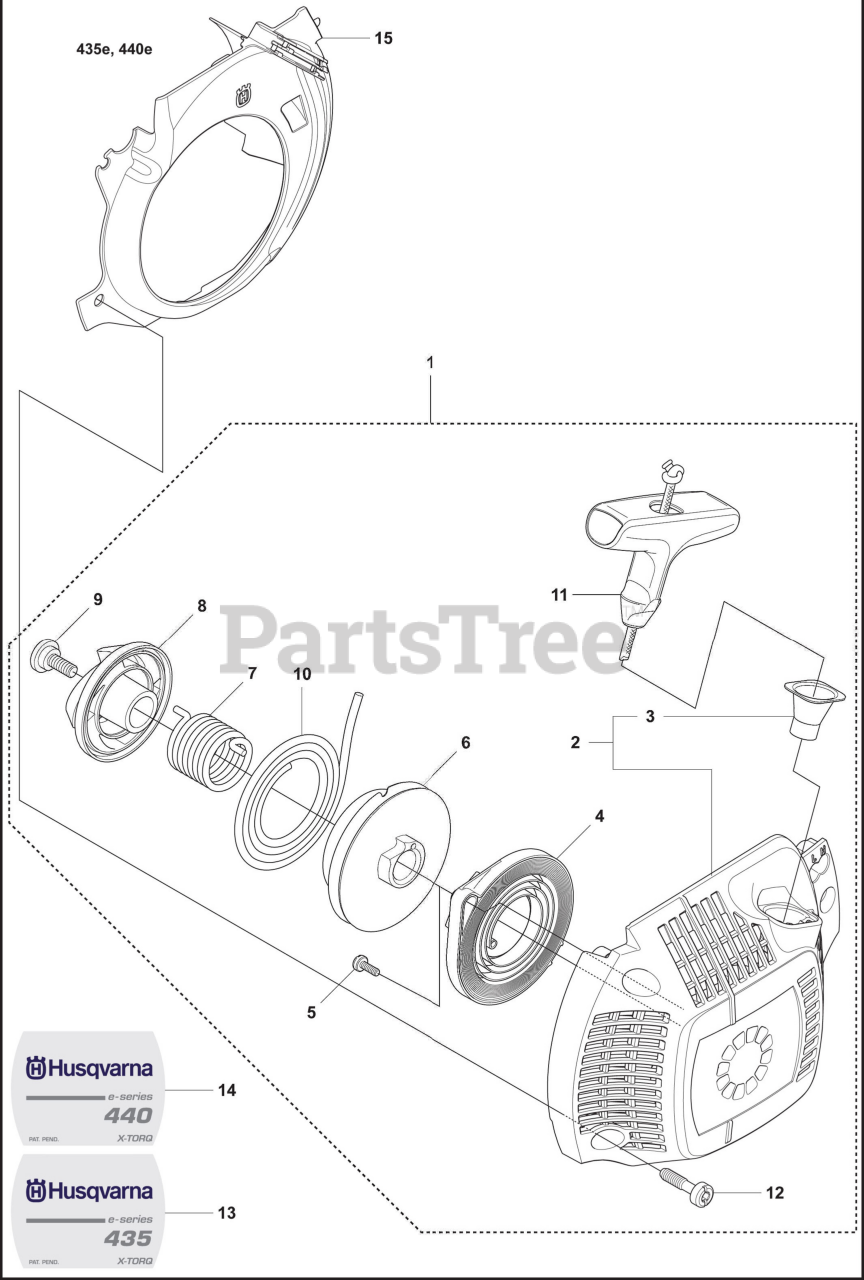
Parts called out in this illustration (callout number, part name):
1	Recoil Starter Assembly
2	Starter Housing
3	Sleeve
4	Cassette Assembly Spring
5	Screw
6	Starter Pulley
7	Spring
8	Starter Hub, EPS
9	Shoulder Screw
10	Starter Rope
11	Handle
12	Recoil Starter Screw
13	Label, 435 Starter
14	Label, 440 Starter
15	Air Cooling Conductor
